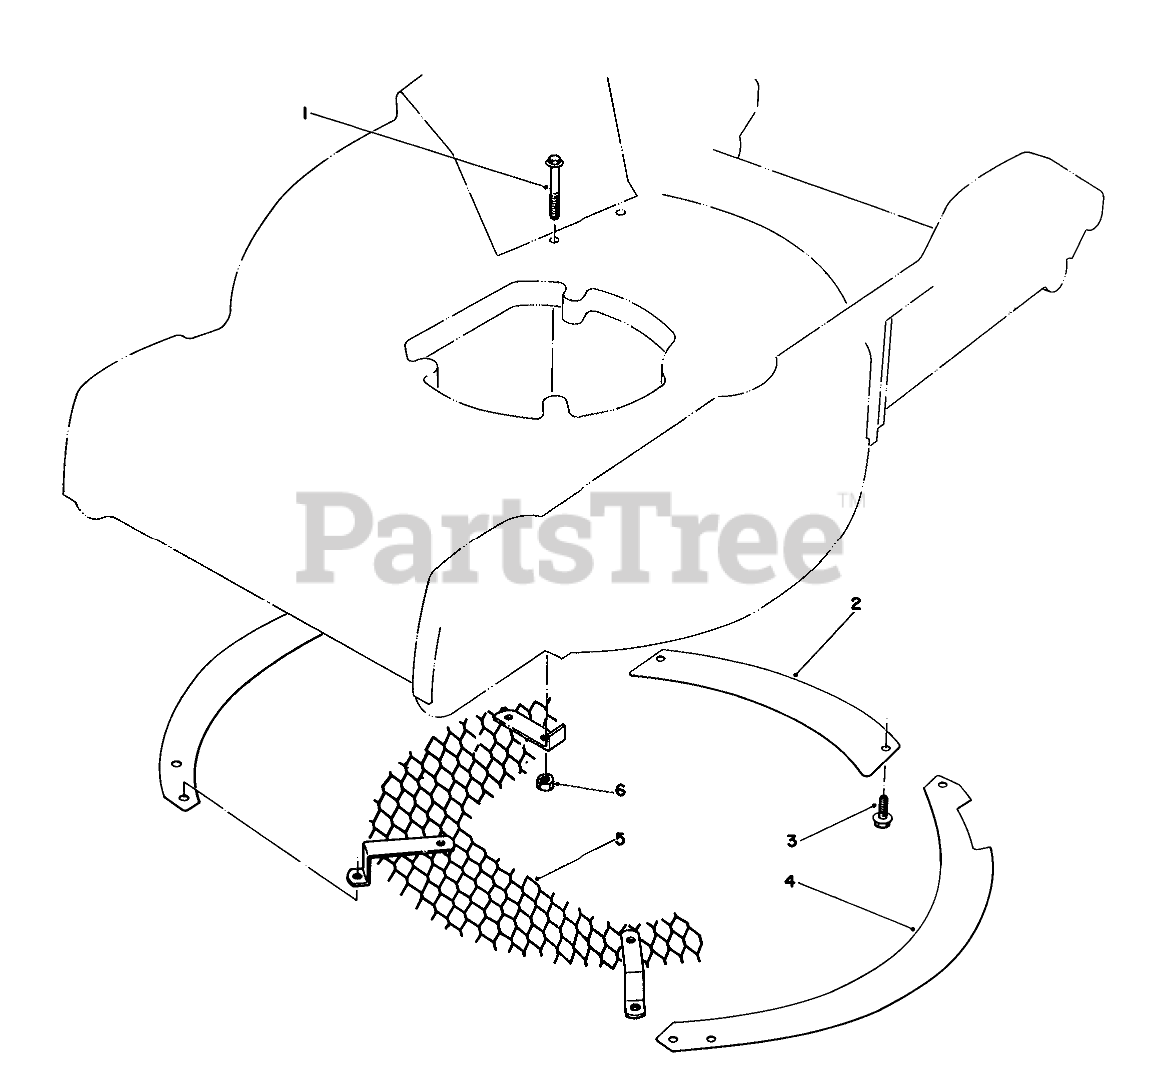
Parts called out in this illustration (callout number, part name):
1	Screw
2	Rear Baffle
3	SCREW
4	Outer Baffle
5	Screen
6	NUT-LOCK
